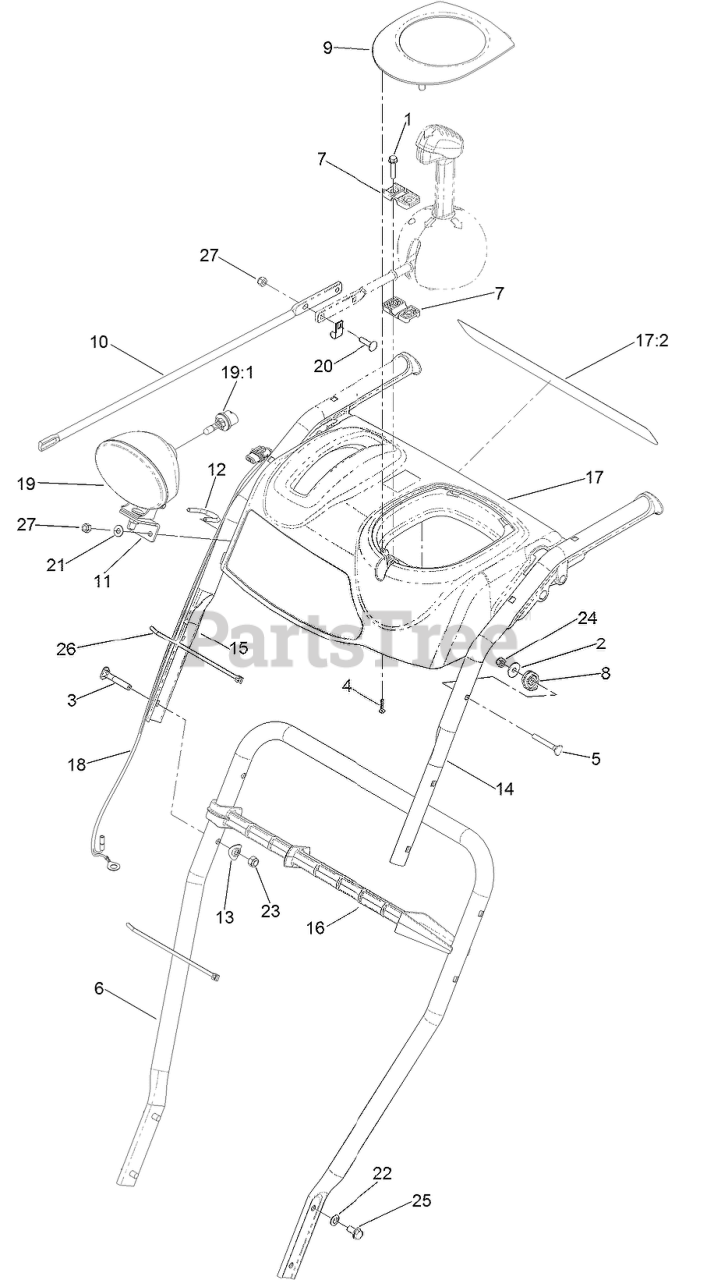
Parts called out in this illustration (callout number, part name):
1	SCREW-PLASTITE
2	WASHER-PLAIN
3	SCREW-HANDLE
4	SCREW-PPH
5	SCREW
6	HANDLE-LOWER
7	SUPPORT-ROD
8	CLAMP-CABLE
9	COVER-PANEL, CONTROL
10	ROD-CHUTE, FRONT
11	BRACKET-LIGHT
12	CLAMP
13	WASHER
14	HANDLE-UPPER, LH
15	HANDLE-UPPER, RH
16	STICK-CLEANOUT
17	PANEL-CONTROL
17:2	DECAL-WARNING
18	HARNESS-WIRE, HEADLIGHT
19	HEADLAMP ASM
19:1	LAMP-12 VOLT
20	SCREW-CARR
21	WASHER-FLAT
22	WASHER-BELLEVILLE
23	NUT-LOCK, NI
24	NUT-LOCK, NI
25	SCREW-HWHTF
26	TIE-CABLE
27	NUT-LOCK, NI
